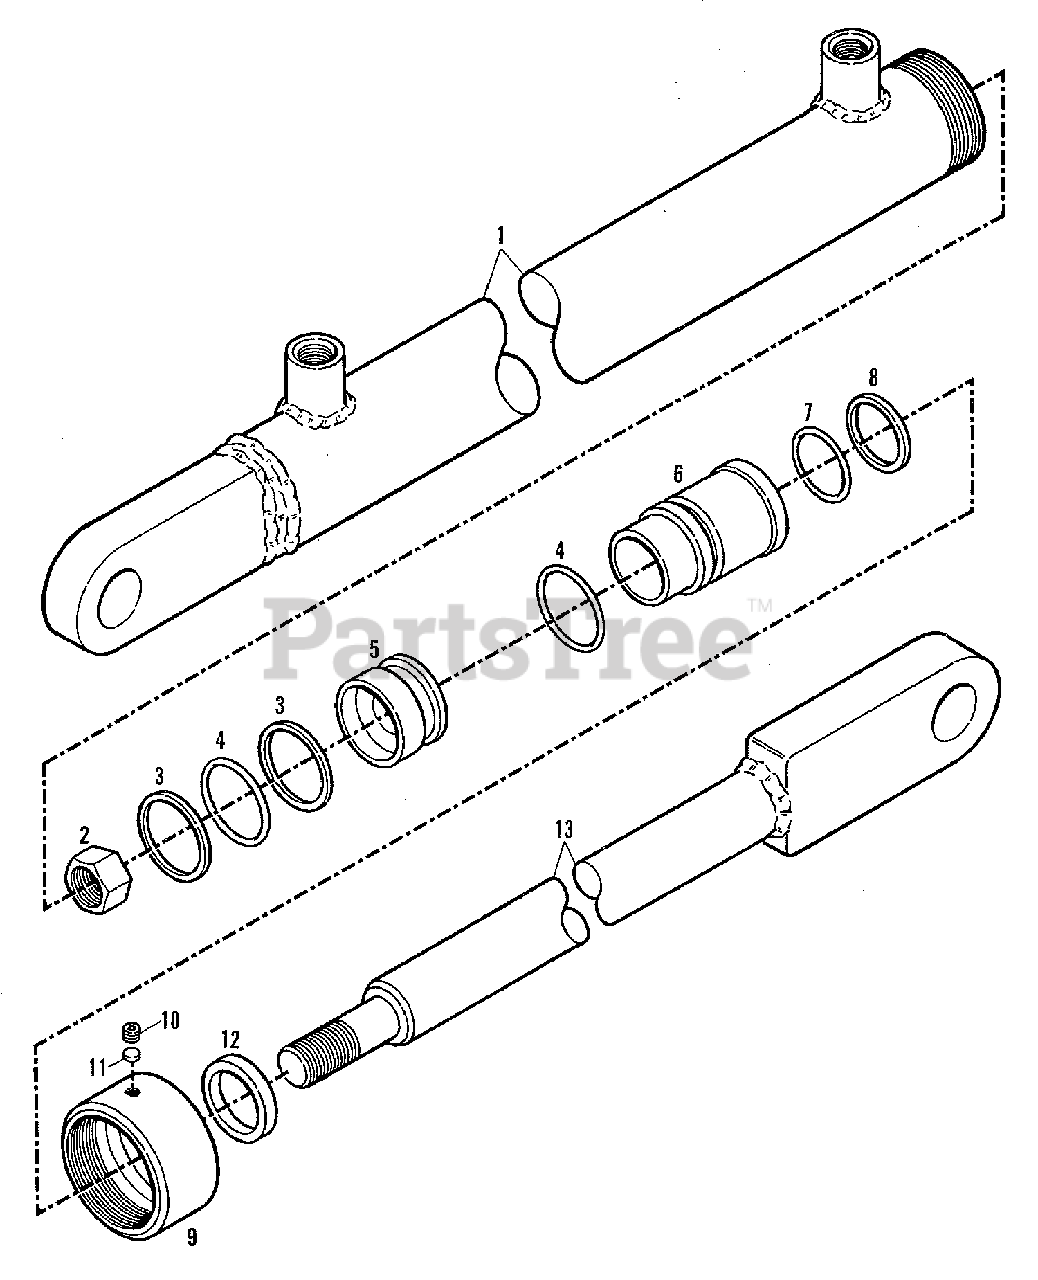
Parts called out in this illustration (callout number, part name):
1	TUBE ASSEMBLY
2	NUT, Piston Rod Assembly
3	WASHER, Backup, Piston
4	O-RING
7	O-RING
8	WASHER, Backup
10	SETSCREW, Cap
11	PLUG, Nylon
12	WIPER, Rod
13	ROD ASSEMBLY, Piston
